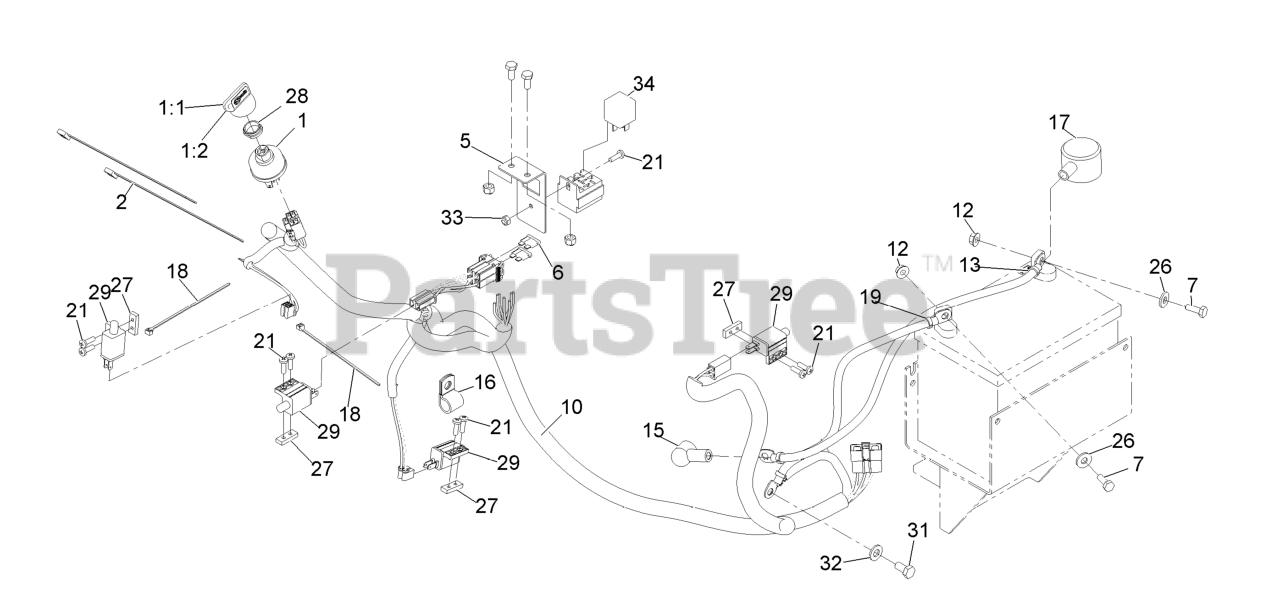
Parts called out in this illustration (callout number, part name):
1:1	KEYS-IGNITION (SPARE PAIR
1:2	KEY-IGNITION
2	TIE-PLASTIC
5	BRACKET-FUSE AND RELAY
6	FUSE-BLADE TYPE, 20 AMP
7	SCREW-HH
13	ASM,POSITIVE BATTERY CABL
15	INSULATOR-SOLENOID
16	CLIP-LOOM
17	INSULATOR-BATTERY
18	TIE-CABLE
19	CABLE-BATTERY, NEGATIVE
21	SCREW-PPH
26	WASHER-FLAT
27	PLATE-TAPPED
28	NUT-SWITCH, IGNITION
29	SWITCH-OPEN, NORMALLY
31	SCREW-HH
32	WASHER-PLAIN
33	NUT-LOCK, NI
